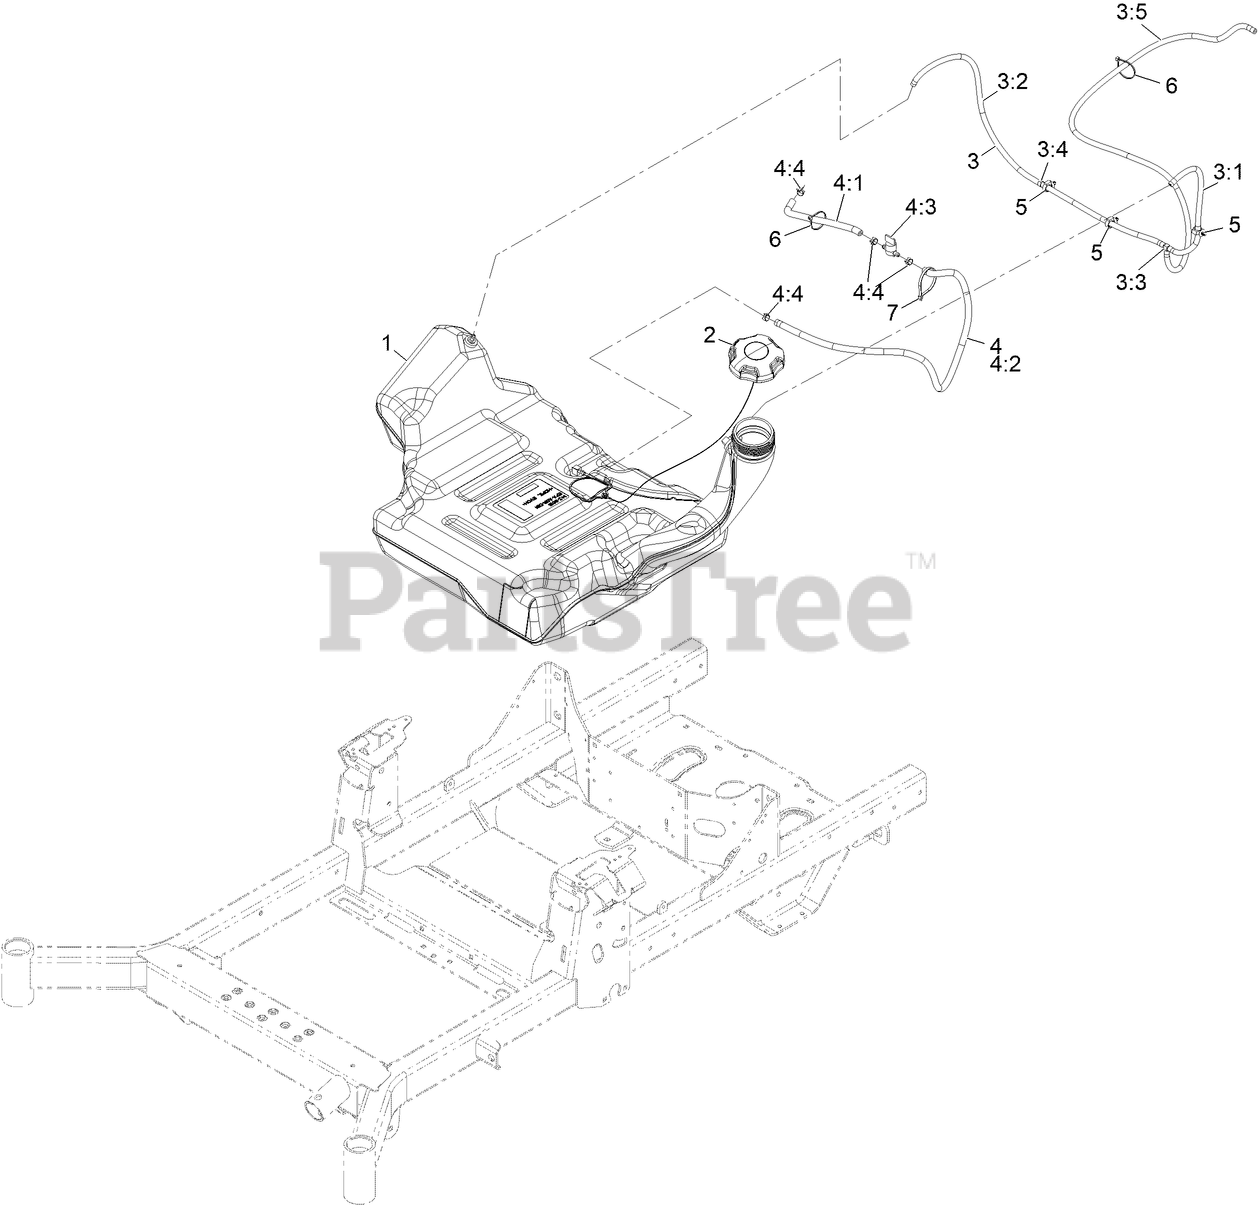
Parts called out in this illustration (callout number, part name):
1	ASM-FUEL TANK
2	CAP-FUEL, RATCHETING
3	ASM-Vent Hose
3:1	HOSE-FUEL
3:2	HOSE-LP
3:3	FITTING-TEE
3:4	Clamp Hose
3:5	Hose-Fuel
4	Fuel Hose ASM
4:1	HOSE-FUEL
4:2	HOSE-FUEL
4:3	VALVE-FUEL
4:4	CLAMP-HOSE
6	TIE-CABLE
7	TIE-CABLE
